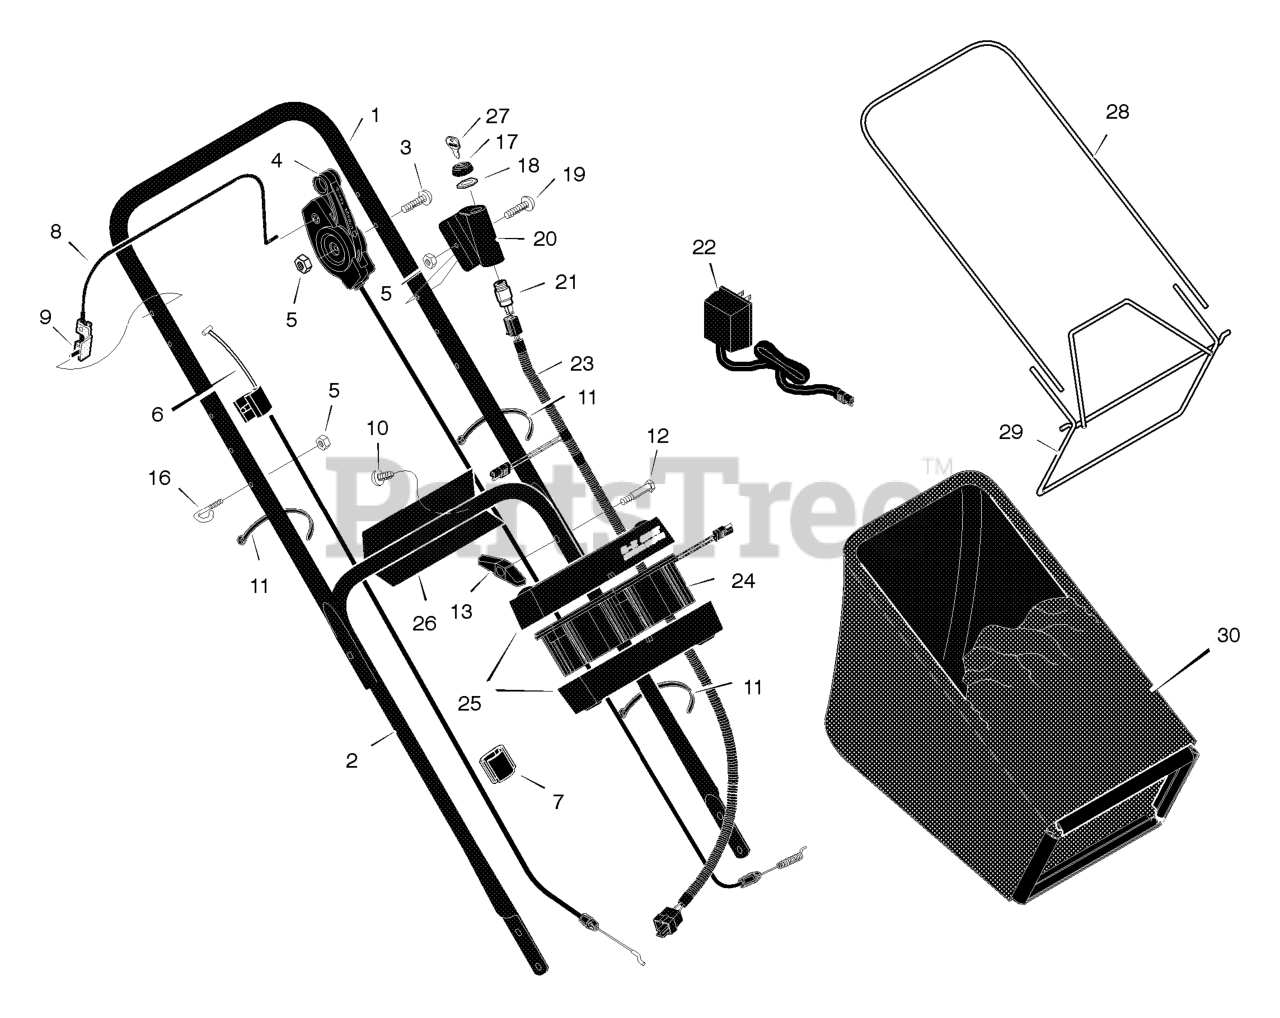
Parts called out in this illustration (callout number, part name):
1	Handle, Upper (Gray)
2	Handle, Lower (Gray)
4	Control, Drive
5	Locknut
6	Cable, Stop
7	Fastener, Double Cable
8	Engine Stop Lever
9	Bracket, Stop Lever
11	Fastener, Cable
13	Knob, Wing
16	Guide, Rope
17	Cap
18	Nut
20	Cover, Ignition
21	Switch Ignition & Key
22	Charger, Battery
23	Harness, Wiring
24	Battery
25	Case, Battery
26	Bracket, Battery
27	Key, Ignition
28	Frame, Top
29	Frame Assembly
30	Bag, Cloth
